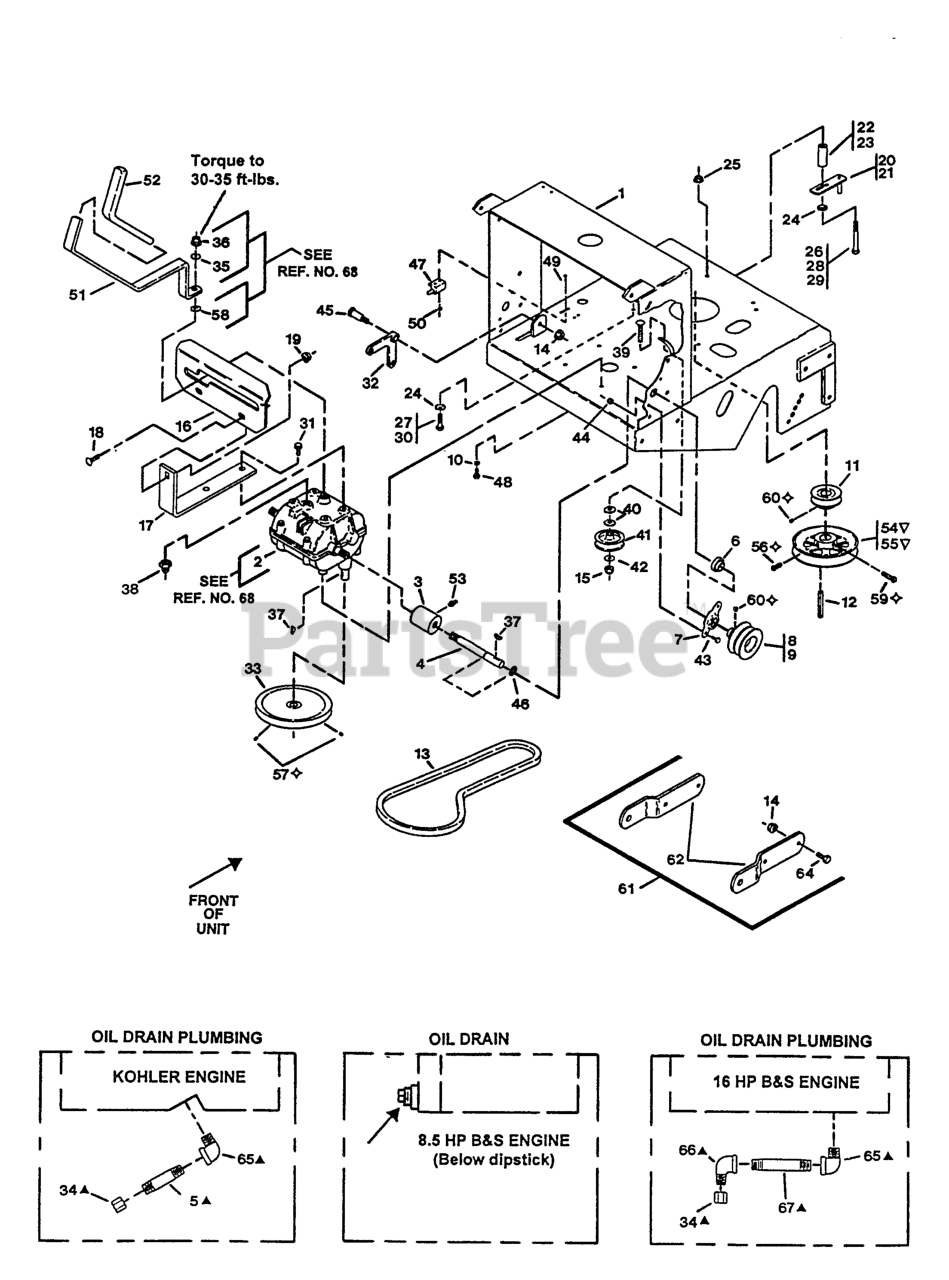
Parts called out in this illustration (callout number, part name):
4	SHAFT-TRANSMISSION
5	NIPPLE
6	BEARING-SHAFT
7	FLANGE-OUTPUT
10	WASHER-LOCK
11	SHEAVE-TRANSMISSION
12	KEY,MACH 1/4X1/4X2-5/8
13	BELT,TRANS DRIVE
17	BRACKET-PLATE, SHIFT
20	GUIDE-BELT
21	GUIDE-BELT
24	WASHER-SPRING
28	SCRW,CAP HH M8X1.25X75M
29	SCRW,CAP HH M8X1.25X75M
32	BELLCRANK
33	SHEAVE-TRANSMISSION
34	CAP-HEX
38	SWITCH-START, NEUTRAL
45	BOLT-SHOULDER
47	SWITCH-OPEN, NORMALLY
54	SHEAVE,BLADE DRIVE
56	SCREW-SET
60	SCREW-SET
61	Sulky Hitch Kit, Metro
62	HITCH-SULKY
65	FITTING-ELBOW-90
66	ELBOW-90 DEG
67	NIPPLE
